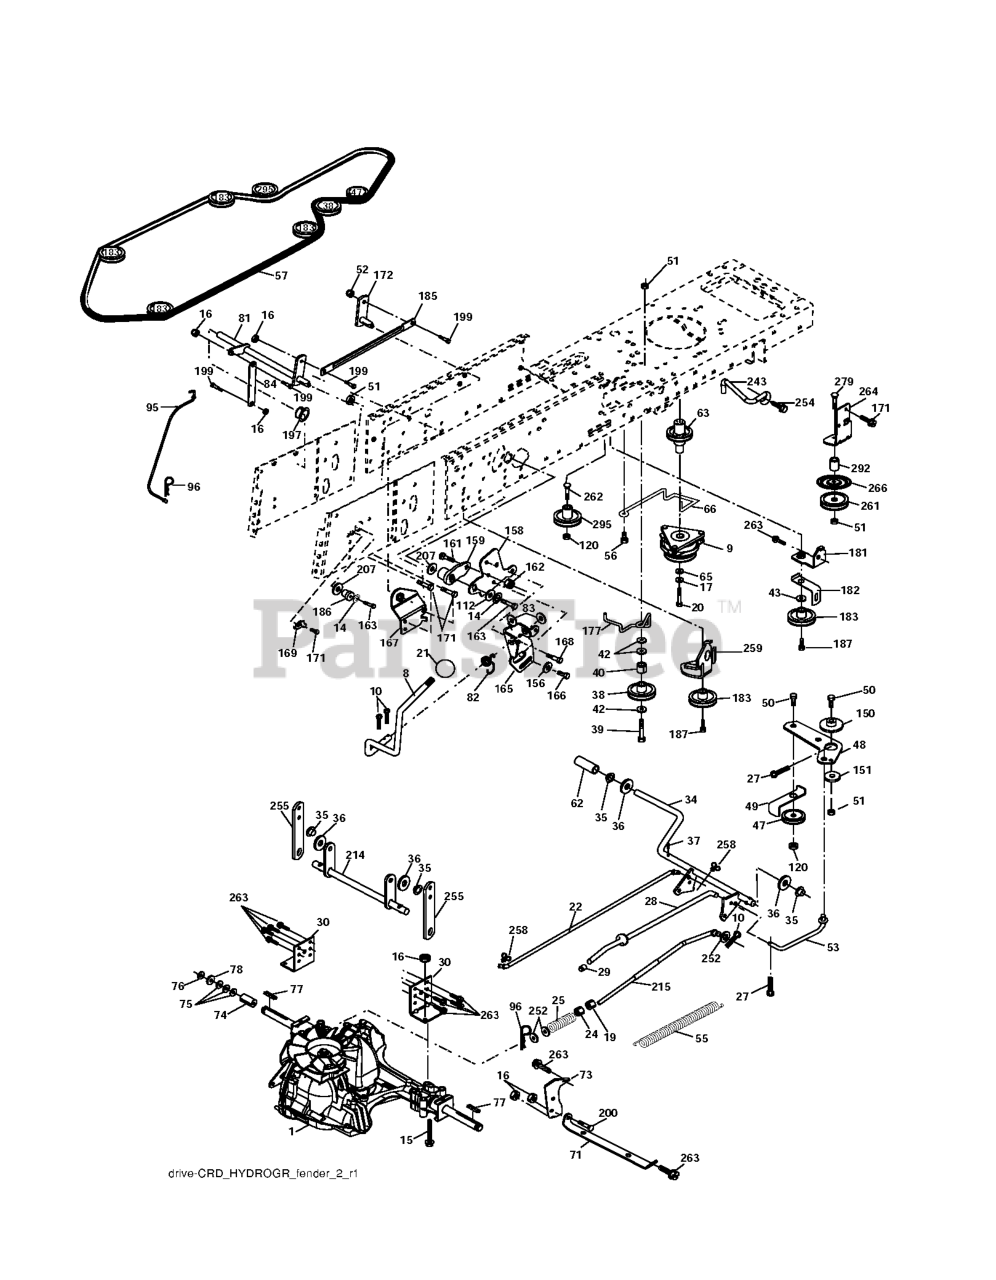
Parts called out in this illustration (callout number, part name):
8	ROD SHIFT FENDER ADJUST LT
9	CLUTCH.ELECTRIC.OGURA.EURO.
10	PIN COTTER
14	LOCKWASHER
15	BOLT HEX 5/16-18 GR 5
16	NUT.71038.31-18.HEX.NYLOCK
19	NUT
20	BOLT HEX 7/16-20X4-1/4"
21	KNOB.DUCKHEAD.1/2
22	ROD
24	NUT
25	SPRING BRAKE ROD
27	COTTER PIN
28	ROD, PARKING BRAKE
29	CAP
30	BRKT, TRNSXLE MNT 20"
34	SHAFT, FOOT PEDAL
35	BEARING.NYLON
37	DRIVE PIN
38	PULLEY.FLAT
42	WASHER
47	IDLER PULLEY
48	BELLCRANK, CLUTCH
49	RETAIN BELT
50	BOLT.3/8-16X1.50
52	LOCKNUT
53	LINK.CLUTCH.7.66.2005
55	SPRING, RETURN LT
56	SCREW.3/8-16
57	V-BELT 113"
62	PEDAL COVER T
63	PULLEY.ENGINE.CVX.LT
65	LOCKWASHER
66	KEEPER BELT ENGINE
71	STRAP TORQUE LH HYDRO
73	STRAP TORQUE RH HYDRO
74	SPACER AXLE
77	SQUARE KEY
81	ASM.CROSS.SHAFT.REAR.CRD.0510
82	SHIFT SPRING
83	WASHER
84	LINK.PNT.TRANSAXLE.0510.CRD
95	LINK
96	RETAINER M
120	NUT LOCK FLG 3/8-16 UNC
150	BUSHING.BELLCRANK.GRD.DR
151	WASHER 12/32X2X10GA
156	WASHER.SRRTD.5/16
158	BRACKET
159	RB HUB.SHIFT
161	BOLT
162	NUT.CROWNLOCK.1/4
165	RP BRACKET
166	CAPSCREW.HXHD.FLG.5/16-18X.625
167	BRACKET.SUPT.SHIFT.CRD
168	BOLT.SHOULDER.5/16-18X
169	PLATE.FASTENING.CROSS.SHAFT
172	LINK
181	BRACKET
182	BELT GUIDE
183	PULLEY.V-IDLER.GRND.DR
185	LINK
186	HUB.TAPERED.ROUND.CRD
187	BOLT.5/16-18X1.25
197	NYLINER SNAP 5/8" ID
199	BOLT SHOULDER 5/16-18 UNC
207	WASHER NYL
214	LEVER
215	ROD
243	BRACKET, ANTI-ROTATION
252	WASHER
254	SCREW 3/8-16X1
255	SHAFT
258	CLIP RETAINER
259	BRACKET
261	FLAT IDLER PULLEY
263	SCREW, 3/8-16X3/4
266	PROTECTOR
292	SPACER
295	PULLEY IDLER COMPOSITE
